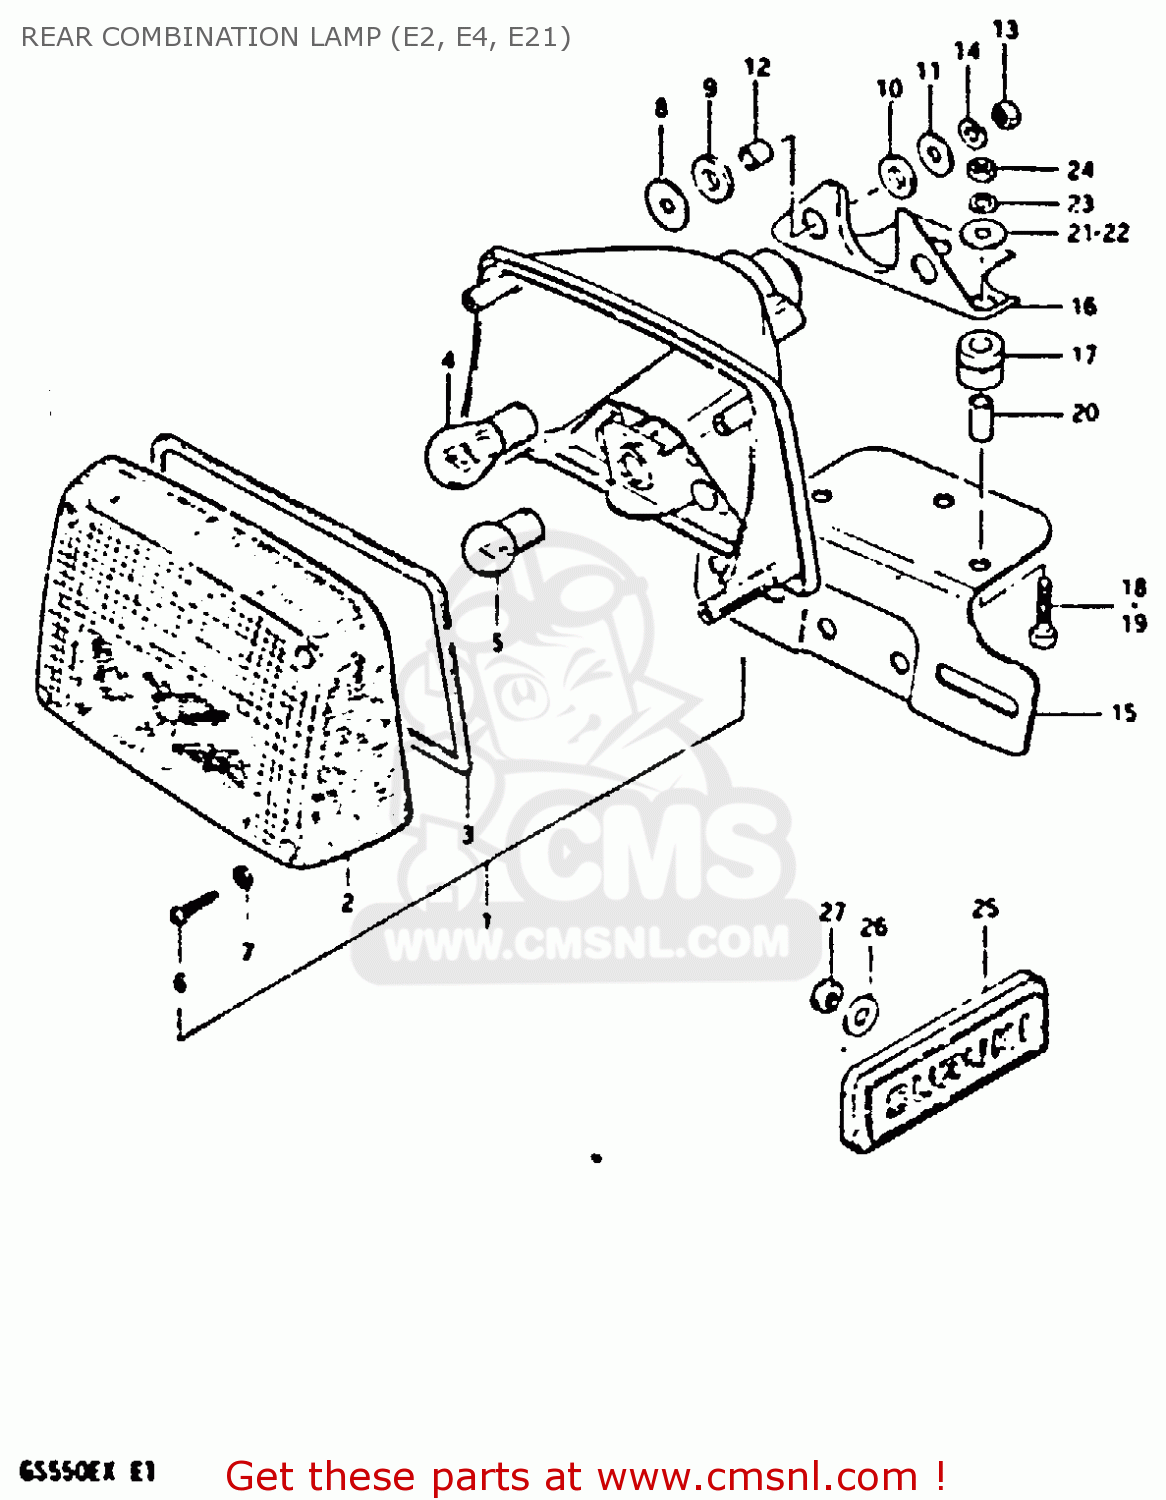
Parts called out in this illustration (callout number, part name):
1	LAMP, REAR COMBINATION
2	LENS
3	GASKET (NAS)
4	BULB 12V21/5W
5	BULB
6	SCREW
7	GASKET (NAS)
8	WASHER
9	CUSHION
10	CUSHION
11	WASHER(6,5X22X1.6)
12	SPACER(6.1X9X7.5)
13	NUT
14	LOCK WASHER
15	BRACKET, LICENCE PLATE
16	BRACKET,LICENSE PLATE
17	CUSHION, BRACKET
18	BOLT
19	BOLT
20	SPACER (6.4X9X15.5)
21	WASHER
22	WASHER
23	LOCK WASHER
24	NUT
25	EMBLEM, REAR SIDE
26	WASHER
27	NUT
